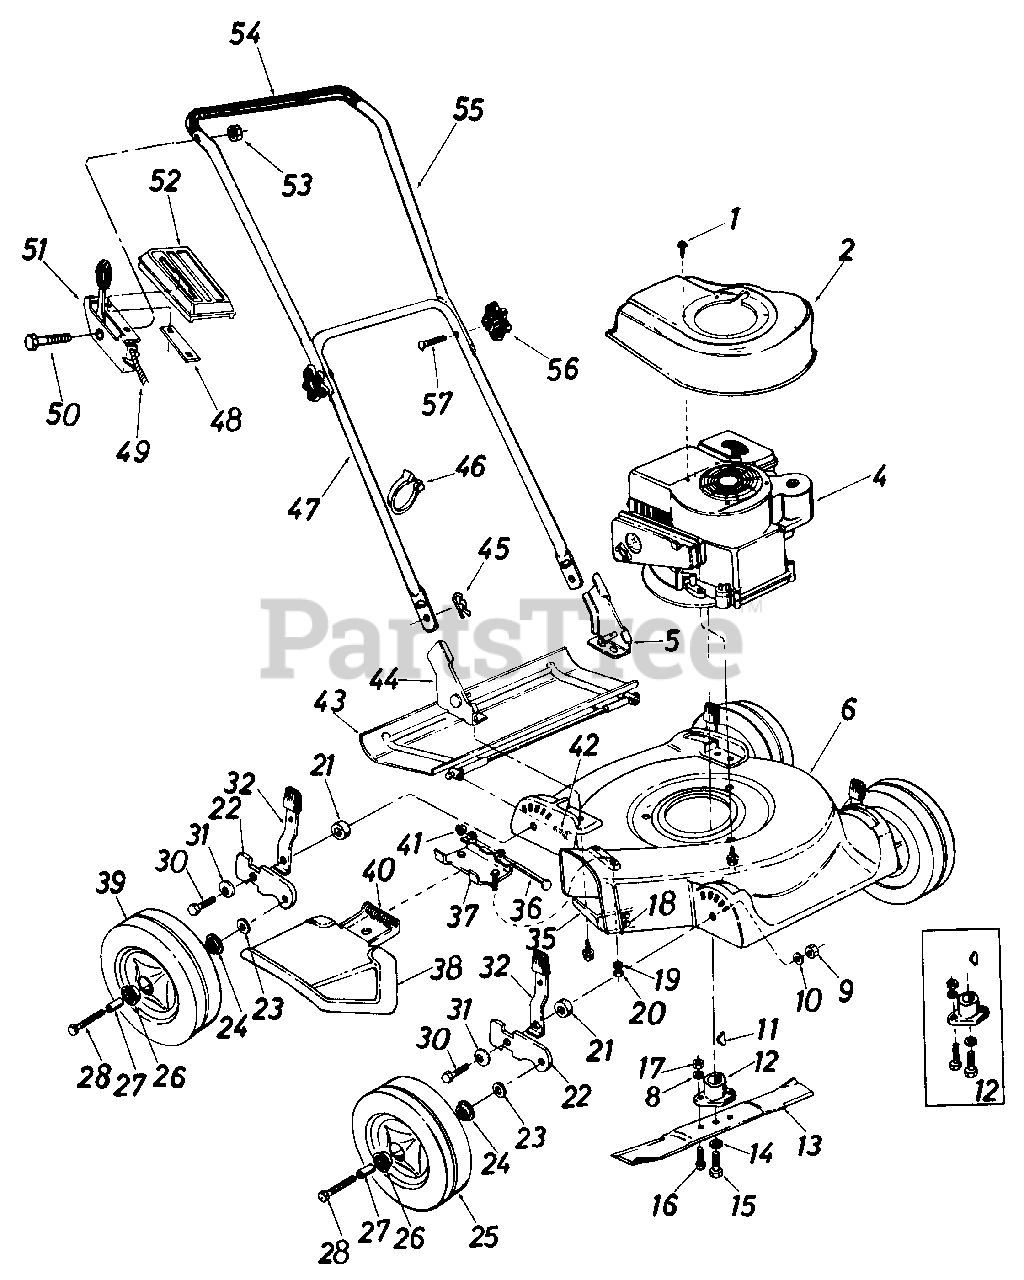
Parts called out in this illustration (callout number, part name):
1	Hex Wash. Hd. AB-Tap Scr. #8 x .38" Lg.
2	Engine Shroud
4	Engine
5	Handle Mount Brkt. - L.H.
6	20" Deck Ass'y.
8	L-Wash. 5/16" I.D.
9	Hex Jam Nut 3/8-24 Thd.
10	L-Wash. 3/8" I.D.
11	#6 Hi-Pro Key 5/32" x 5/8" Dia.
12	Blade Adapter Kit
13	20" Blade
14	L-Wash. 3/8" I.D. - H.D.
15	Hex Bolt 3/8-24 x 1.50" Lg. - H.T.
16	Hex Bolt 5/16-24 x 1.00" Lg. - H.T.
17	Hex Nut 5/16-24 Thd.
18	Hex Bolt 1/4-20 x .75" Lg.
19	L-Wash 1/4" I.D.
20	Hex Nut 1/4-28 Thd.
21	Shoulder Spacer
22	Pivot Bar
23	Belleville Washer
24	Flanged Ball Bearing 1/2" I.D.
25	7" Front Wheel Ass'y. Comp.
26	Flanged Ball Bearing 3/8" I.D.
28	Hex Bolt 3/8-16 x 1.75" Lg.
30	Hex Bolt 3/8-24 x 1.50" Lg. - H.T.
31	Belleville Washer
32	Spring Lever
35	Internal Bar
36	Pivot Pin
37	Adapter Plate Ass'y.
38	Chute Deflector Ass'y. Comp.
39	Rear Wheel Ass'y. Comp.
40	Torsion Spring
41	Push Nut 1/4" Rod
42	Hex Bolt 1/4-28 x .62" Lg.
43	Rear Shield Ass'y.
44	Handle Mount Brkt. - R.H.
45	Hairpin Cotter
46	Cable Tie
47	Lower Handle
48	Speed Nut #8-32 - Twin Type
49	Conduit and Wire
50	Hex Bolt 1/4-20 x 1.50" Lg.
51	Throttle Control
52	Plastic Cover
53	Hex Cent. L-Nut 1/4-20 Thd.
55	Upper Handle
56	Hand Knob
57	Curved Hd. Bolt 5/16-18 x 1.75" Lg.
